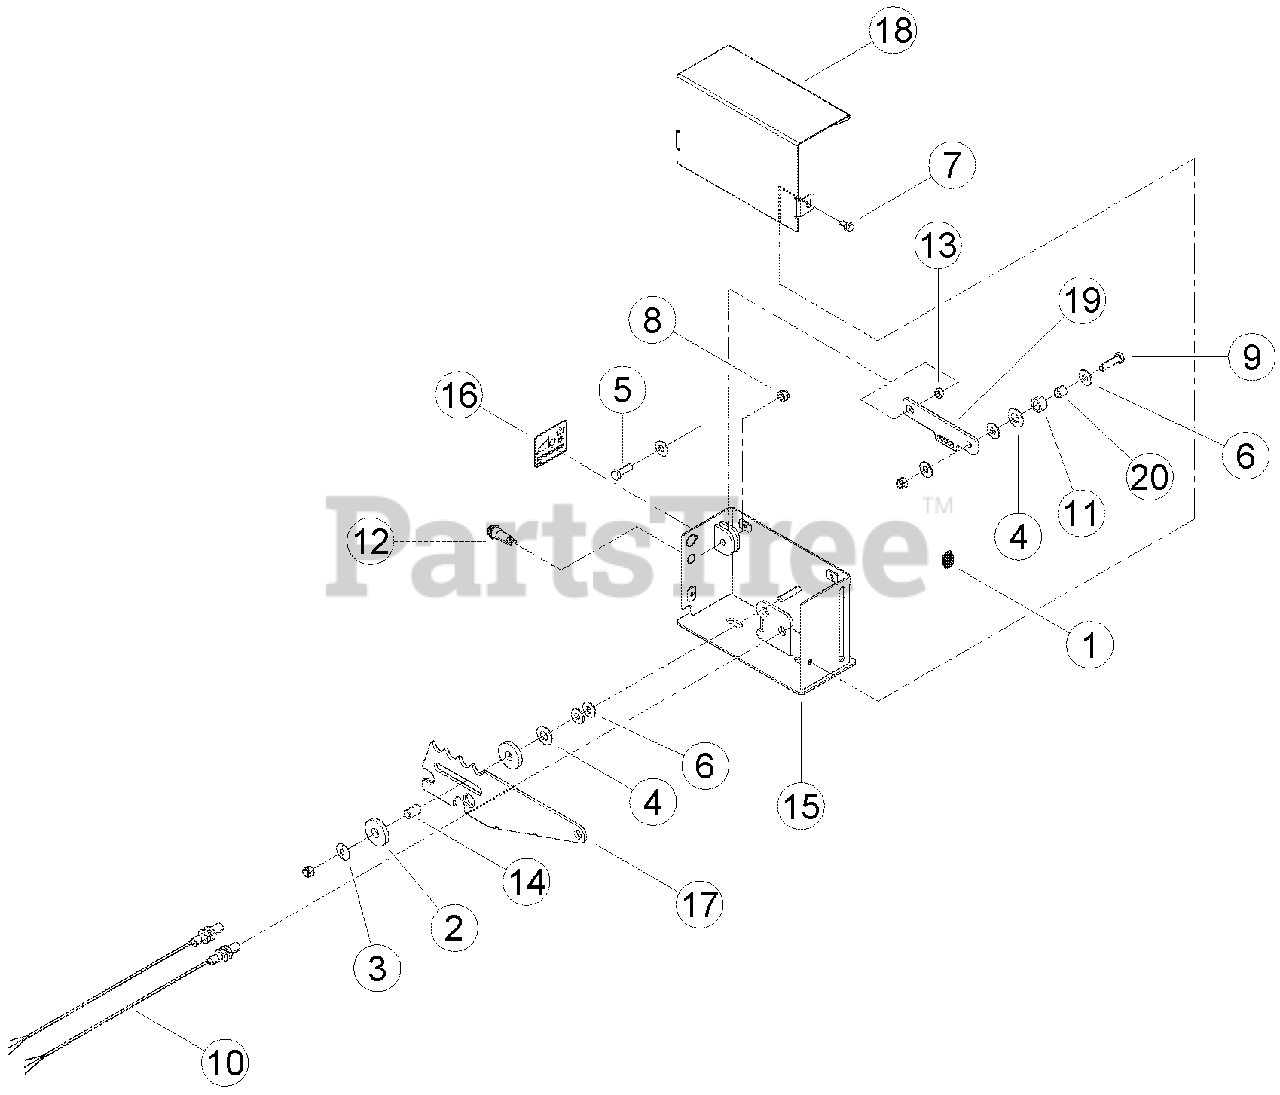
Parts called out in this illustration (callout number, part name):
1	SPRING, CONTROL BAR
2	WASHER, UHM SPACER .515 ID X 1.50 OD
3	WASHER, SPRING
4	WASHER, 1/2 SAE FLAT ZP
5	BOLT, 5/16 X 1 HHCS GR5 NC ZP
6	WASHER, 5/16 FLAT ZP
7	BOLT, 1/4 X 1/2 SERR FLANGE GR5 ZP
8	NUT, 5/16 NYLOCK
9	BOLT, 5/16 X 1-1/4 HHCS GR5 NC ZP
10	SENSOR, PROXIMITY. (WAS 18472-00. REPLACED AND SUPERSEDED. FOR SERVICE ORDER PN 32108-00, PROXIMITY SENSOR).
11	ROLLER, NYLON .750 OD X .502 ID X .440
12	LED, TRI-COLOR 12V 3-TERMINAL BASE
13	SPACER, IDLER PIVOT
14	SPACER, .50 X .775
16	DECAL, RESET/OVERRIDE
17	BAR, SWITCH CONTROL
18	COVER, CONTROL BOX
19	LINK, DETENT
20	SPACER, .50 OD X .35 ID X .47
